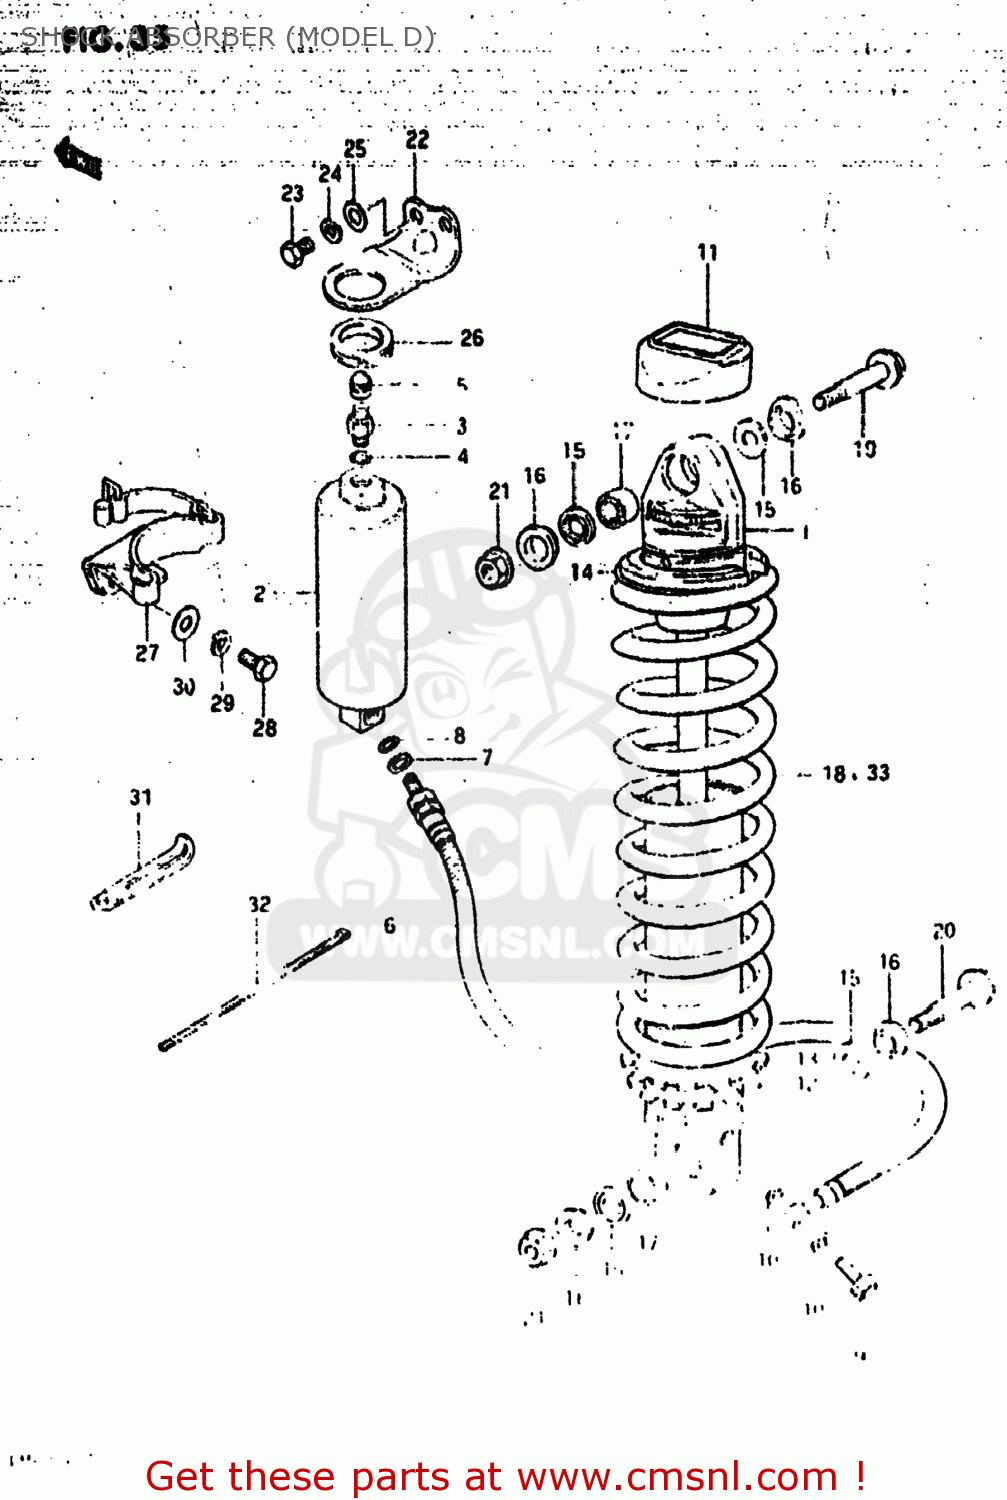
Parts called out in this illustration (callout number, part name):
1	ABSORBER ASSEMBLY,REAR SHOCK
2	RESERVE TANK,REAR SHOCK
3	VALVE,FRONT FORK AIR
4	O-RING
5	CAP
6	HOSE,REAR SHOCK ABSORBER
7	WASHER,REAR SHOCK HOSE
8	O-RING,RESERVE TANK
9	BOLT,REAR SHOCK ABSORBER
10	GASKET (NAS)
11	CAP
12	GUIDE,SPRING
13	SPRING GUIDE
14	GUIDE,REAR SHOCK ABSORBER SPRING
15	DUST SEAL,LWR
16	COLLAR
17	BEARING
18	SPRING
19	BOLT
20	BOLT(10X54)
21	NUT
22	BRACKET,RESERVOIR TANK
23	BOLT
24	LOCK WASHER
25	WASHER
26	CUSHION,RESERVOIR TANK
27	BRACKET,RESERVOIR TANK
28	BOLT, UPPER
29	LOCK WASHER
30	WASHER
31	CLAMP
32	CLAMP
33	SPRING
